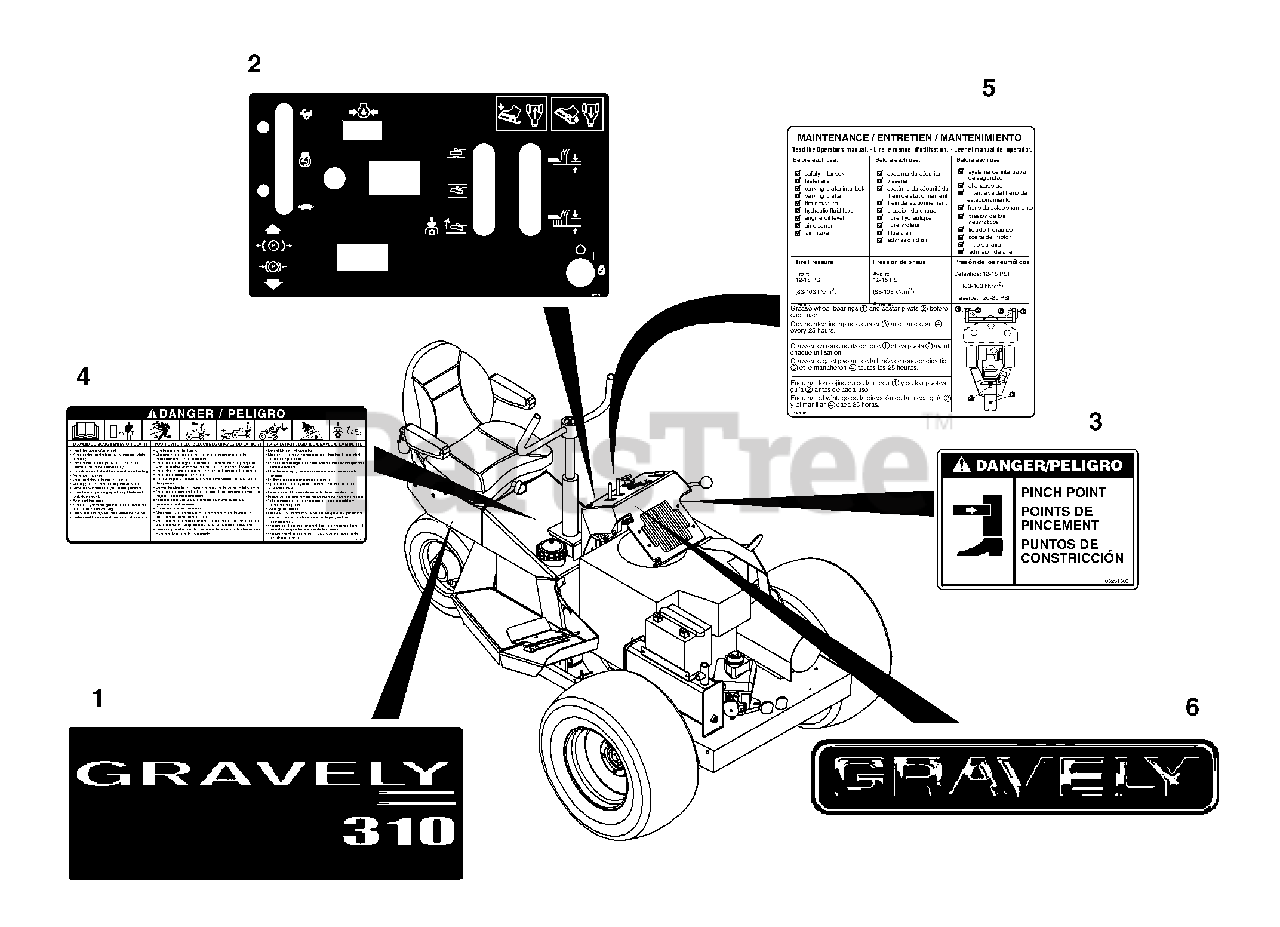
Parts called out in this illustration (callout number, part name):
1	Decal, PM-310
2	Decal, PM-310 Panel
3	Decal, Pinch Point
4	Decal, PM-310 Danger
5	Decal, PM-310 Maintenance
6	Decal, Gravely Logo
